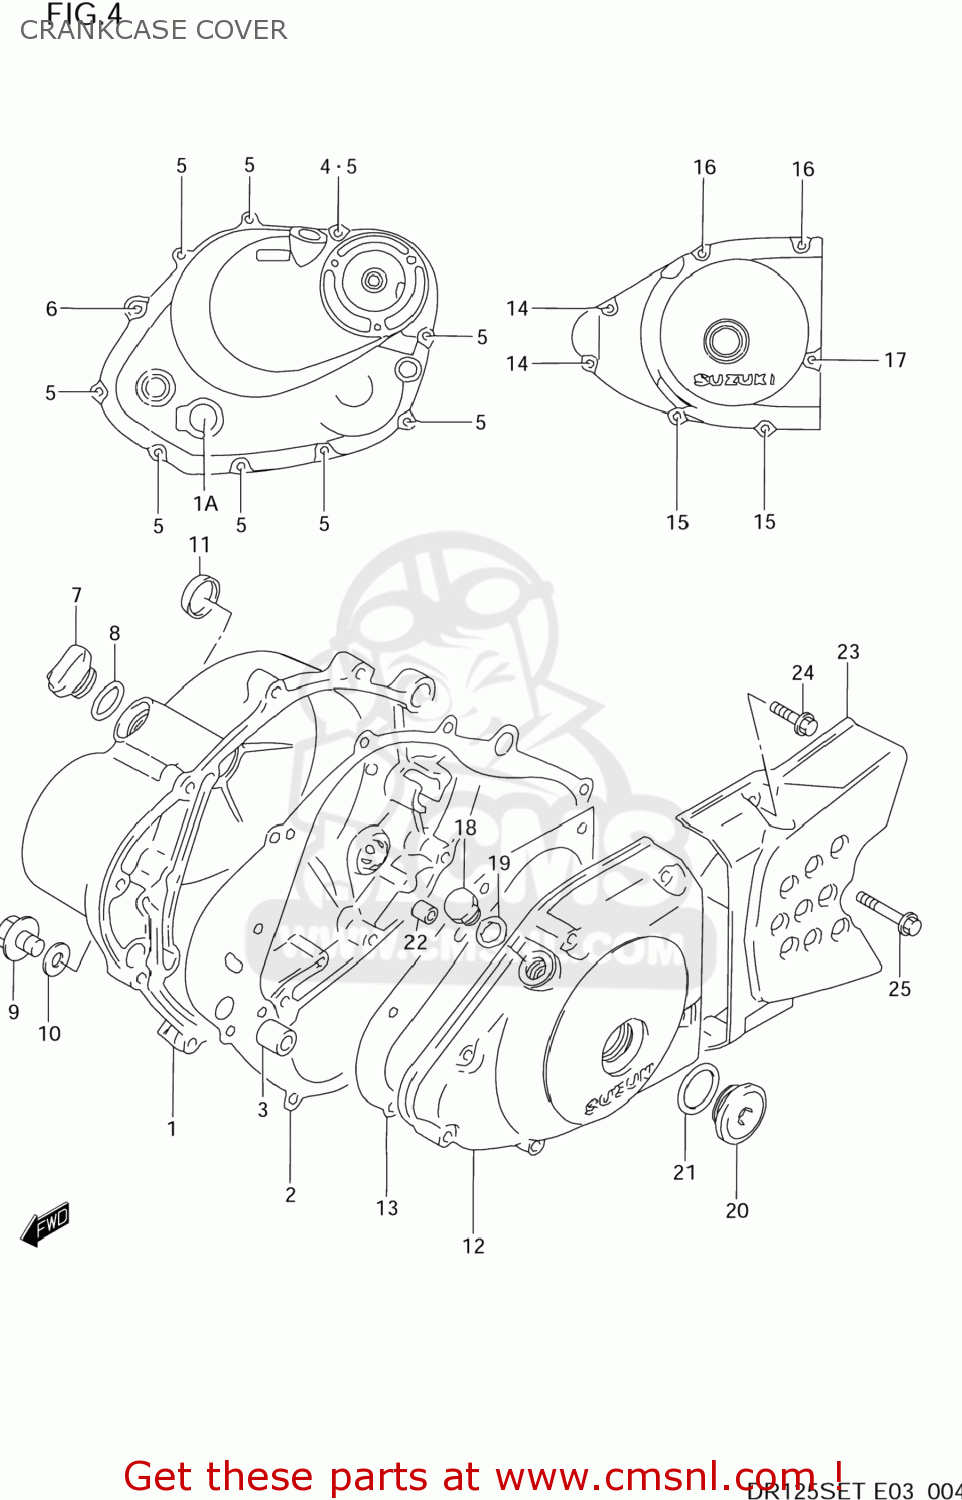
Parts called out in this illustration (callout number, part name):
1	COVER,CLUTCH
1A	LENS,OIL LEVEL CHECK
2	GASKET,CLUTCH COVER (NAS)
3	PIN
4	GASKET(5.8X13X1.2) (NAS)
5	BOLT,G/S SWITC
6	BOLT
7	PLUG
8	O RING(D:3.1,ID:16.8)
9	PLUG(14X12)
10	GASKET(13.8X18.8X4.8) (NAS)
11	PLUG,CLUTCH COVER KICK
12	COVER,MAGNETO
13	GASKET,MAGNETO COVER (NAS)
14	BOLT,G/S SWITC
15	BOLT
16	BOLT
17	BOLT
18	PLUG,12X9
19	GASKET(12.1X16.2X3.7) (NAS)
20	PLUG(26X9)
21	O RING(D:3.1,ID:22.7)
22	PIN
23	COVER,ENGINE SPROCKET
24	SCREW
25	BOLT
